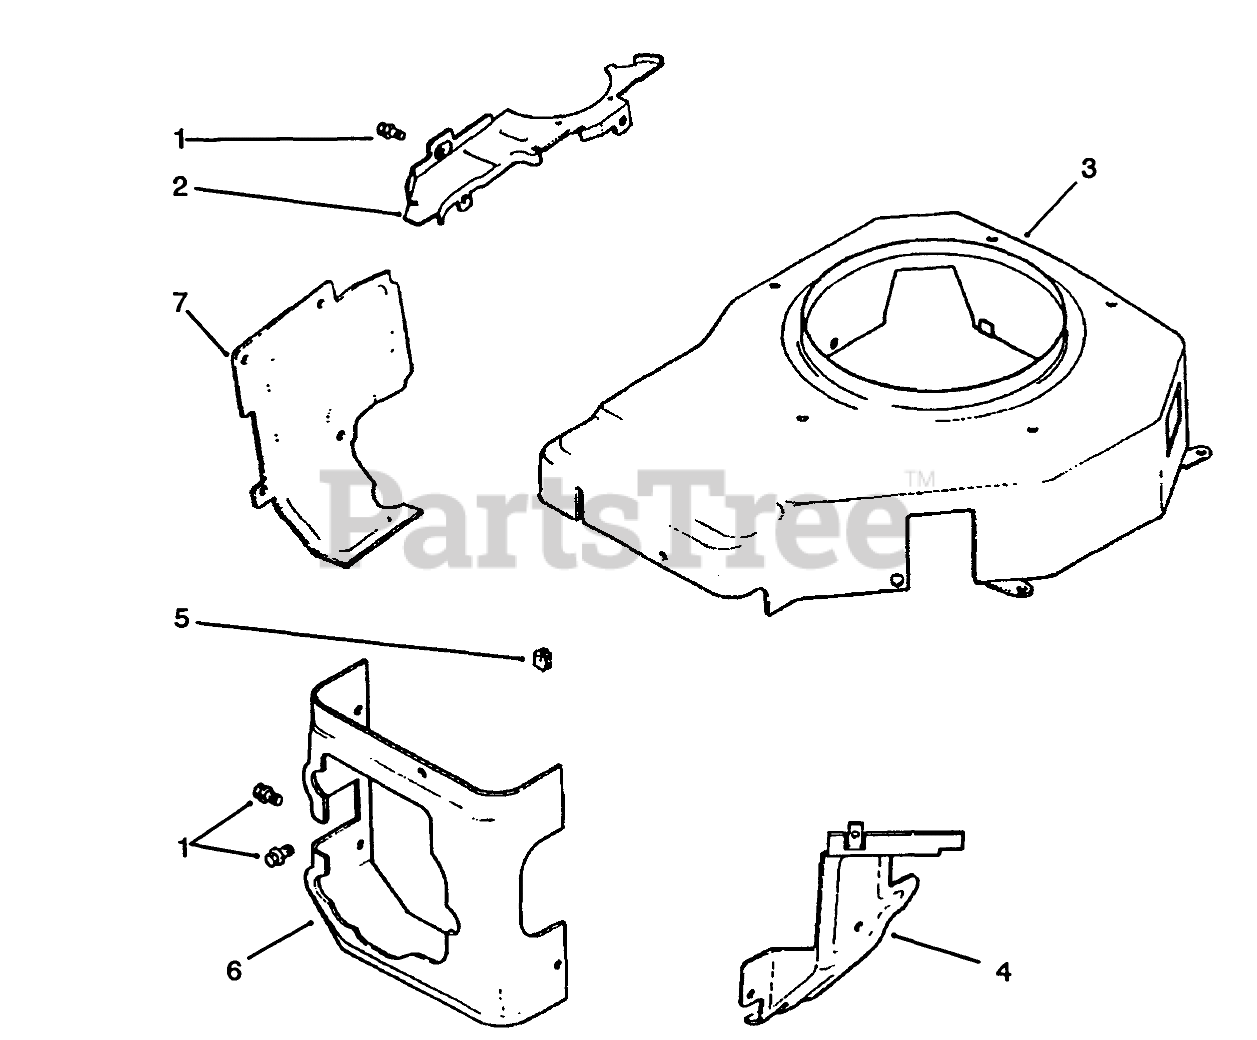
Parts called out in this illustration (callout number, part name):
1	Screw M5x0.8x10 (Only On: 72042, 72063, 72062, 72043)
2	Plate-Blower Housing (Only On: 72042, 72063, 72062, 72043)
3	Housing-Blower (Only On: 72042, 72063, 72062, 72043)
4	Baffle-Carburetor (Only On: 72042, 72063, 72062, 72043)
5	Grommet-Blower Housing (Only On: 72042, 72063, 72062, 72043)
6	Baffle-Cylinder Head (Only On: 72042, 72063, 72062, 72043)
7	Baffle-Cylinder Barrel (Only On: 72042, 72063, 72062, 72043)
